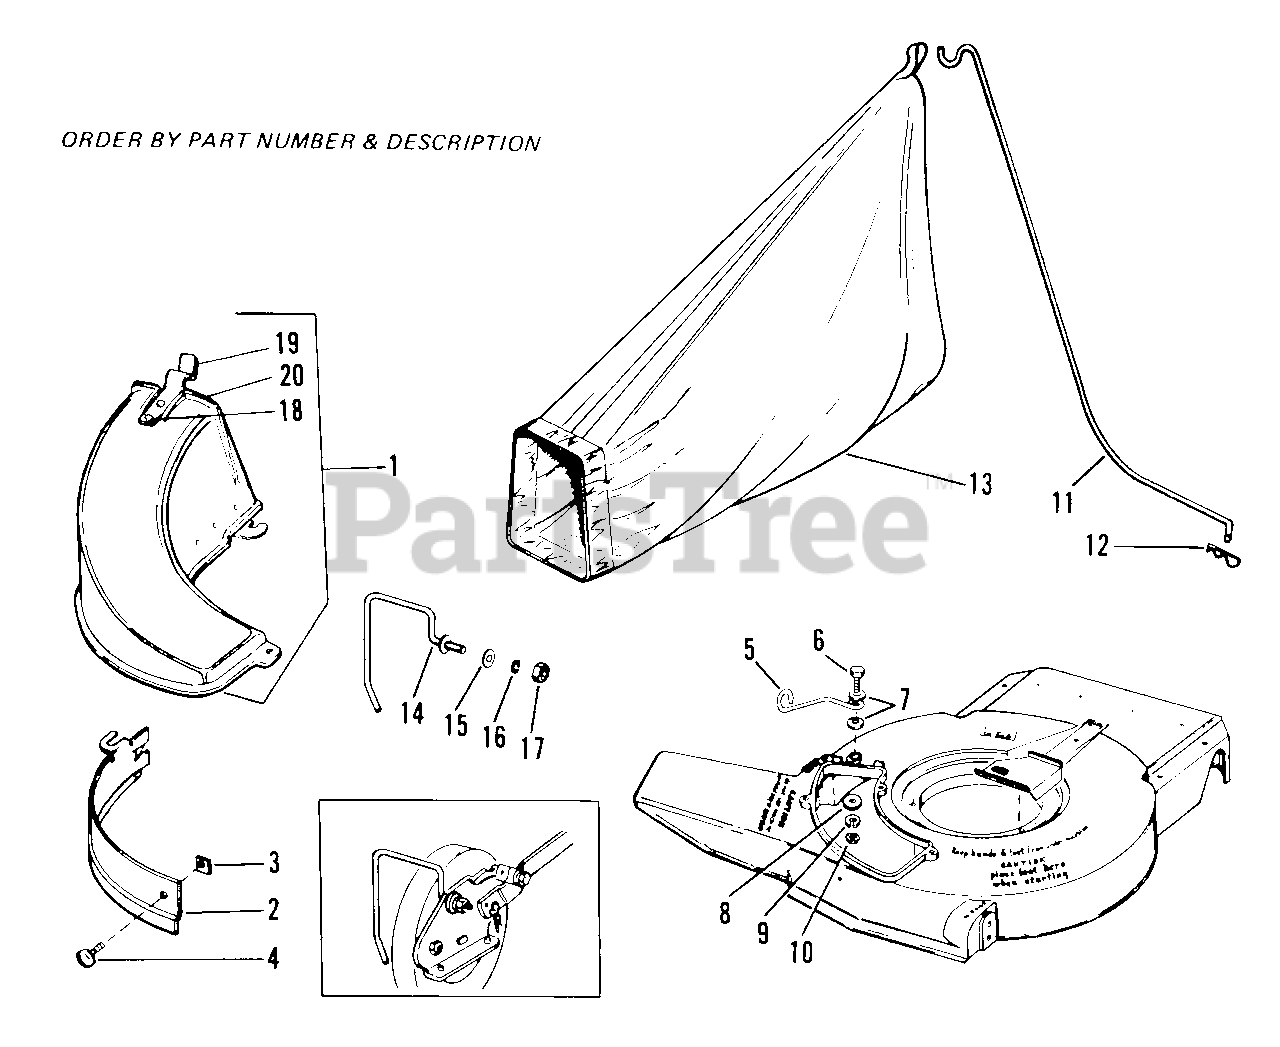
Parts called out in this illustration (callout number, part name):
1	CHUTE ASSY
3	NUT, Speed
4	SCREW, Thumb, 1/4-20 x 5/8
5	GUARD, Bag
6	CAPSCREW, Hex, 1/4-20 x 1
7	WASHER, Plain, 1/4
9	LOCKWASHER, 1/4 916964
10	NUT, Full Hex, 1/4-20
11	ROD, Support Bag
12	CLIP, Hairpin
14	GUARD, Bag
15	WASHER, Plain, 5/16
16	LOCKWASHER, 5/16
17	NUT, Hex Full, 5/16-18
20	CLIP, Plate
